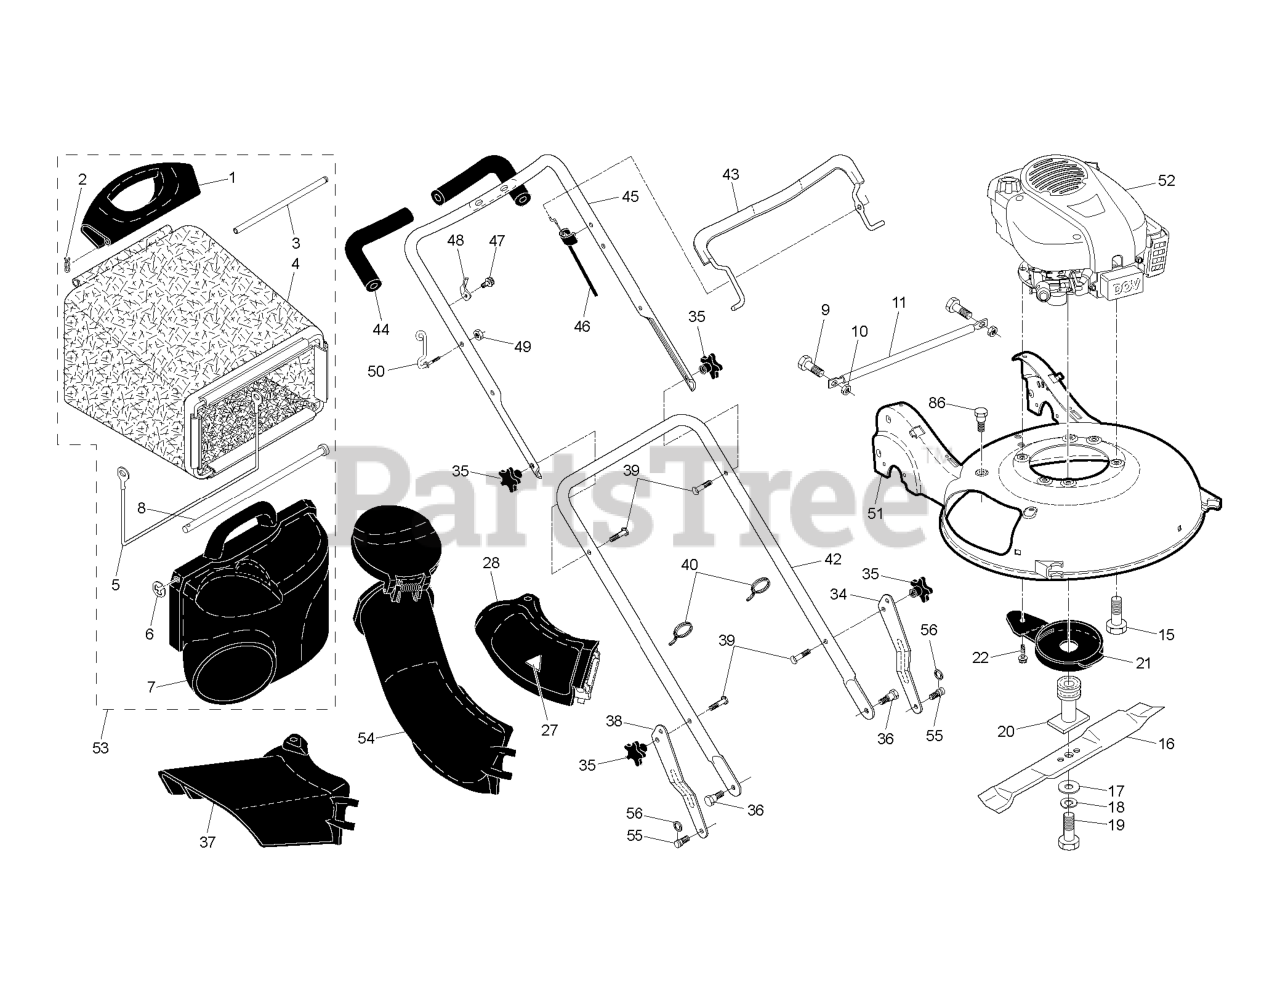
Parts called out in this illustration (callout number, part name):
1	HANDLE.GRASSBAG.REAR.H-GRAY
2	COTTER PIN (3 2)(2 2MC)
3	ROD.REAR.HANDLE.YELLOW
5	FRAME, GRASSBAG
7	DOOR, GRASSBAG
8	ROD, PIVOT
10	LOCKNUT.NYLOC.1/4-20
11	TUBE, REAR SKIRT
15	BOLT 3/8-16X1-1/8
16	Blade, 21"
17	WASHER,HARDEN
18	LOCKWASHER
19	BOLT.HD.HEAD.3/8-24X2.50 (2 2)
20	ADAPTER.BLADE
21	DEBRIS SHEILD
22	SCREW 1/4X20
27	DECAL.INTERNATIONL.CUTFINGER
34	ADJUSTMENT BRACKET, LOWER LH
35	KNOB.HANDLE.PLASTIC.STAR.BLACK
36	SCREW.5/16X.680.TRIM.H
38	BRACKET.ADJ.LOWER.HDL.RT.GREY
39	BOLT, HANDLE 5/16-18X1.75
40	TIE GUIDE
42	HANDLE.LOWER.GREY
43	BAIL.CONTROL.MZR.BS.ORANGE
44	GRIP.HANDLE.FOAM.WIDE.(1 SIDE)
45	HANDLE.ASM.UPPER.W/GRIP
46	CABLE.MZR.SNAP-IN
48	BRACKET.UPSTOP.RT
49	NUT
50	GUIDE.ROPE.WALK.MOWER
53	Grassbag Assembly, Complete
55	STUD.SHOULDER.T45.BZP
56	E-RING 7/16 RE
